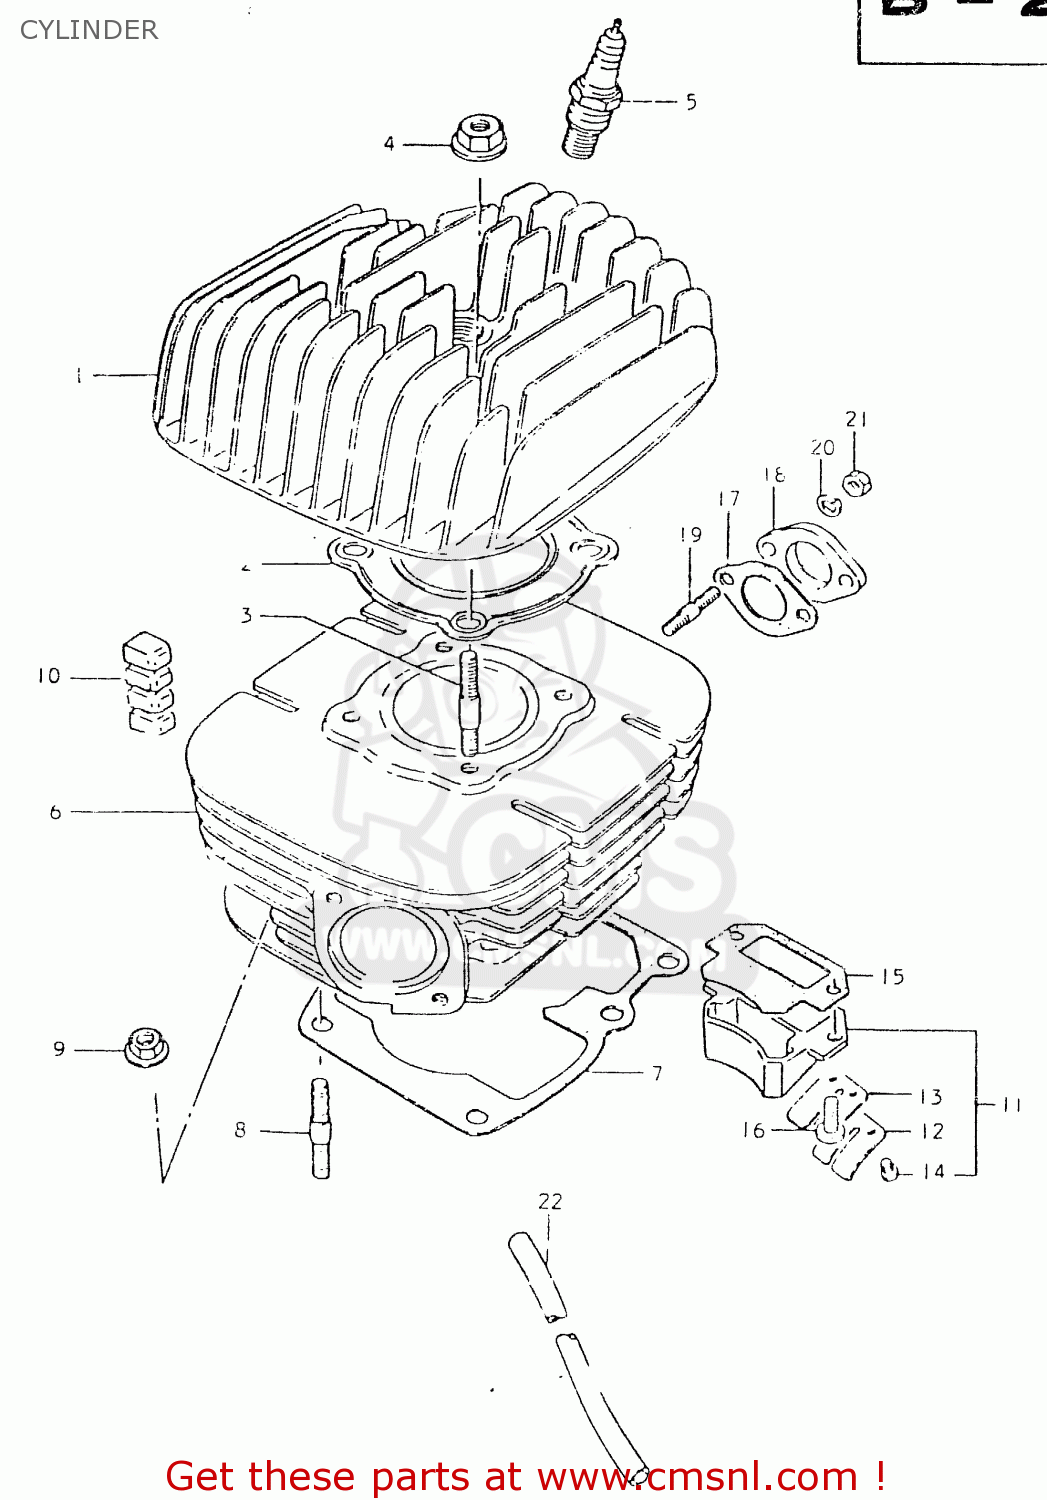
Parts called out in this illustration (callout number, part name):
1	HEAD,CYLINDER
2	GASKET,CYLINDER HEAD (MCA)
3	STUD BOLT
4	NUT
5	SPARK PLUG
6	CYLINDER
7	GASKET,CYLINDER (MCA)
8	STUD 8X25
9	NUT
10	PAD,CYLINDER
11	VALVE ASSEMBLY,REED
12	STOPPER,REED VALVE
13	VALVE,REED
14	SCREW,REED VALVE
15	GASKET,REED VALVE (MCA)
16	SCREW
17	GASKET,CARBURETOR (MCA)
18	INSULATOR,CARBURETOR
19	STUD BOLT
20	LOCK WASHER
21	NUT
22	HOSE
